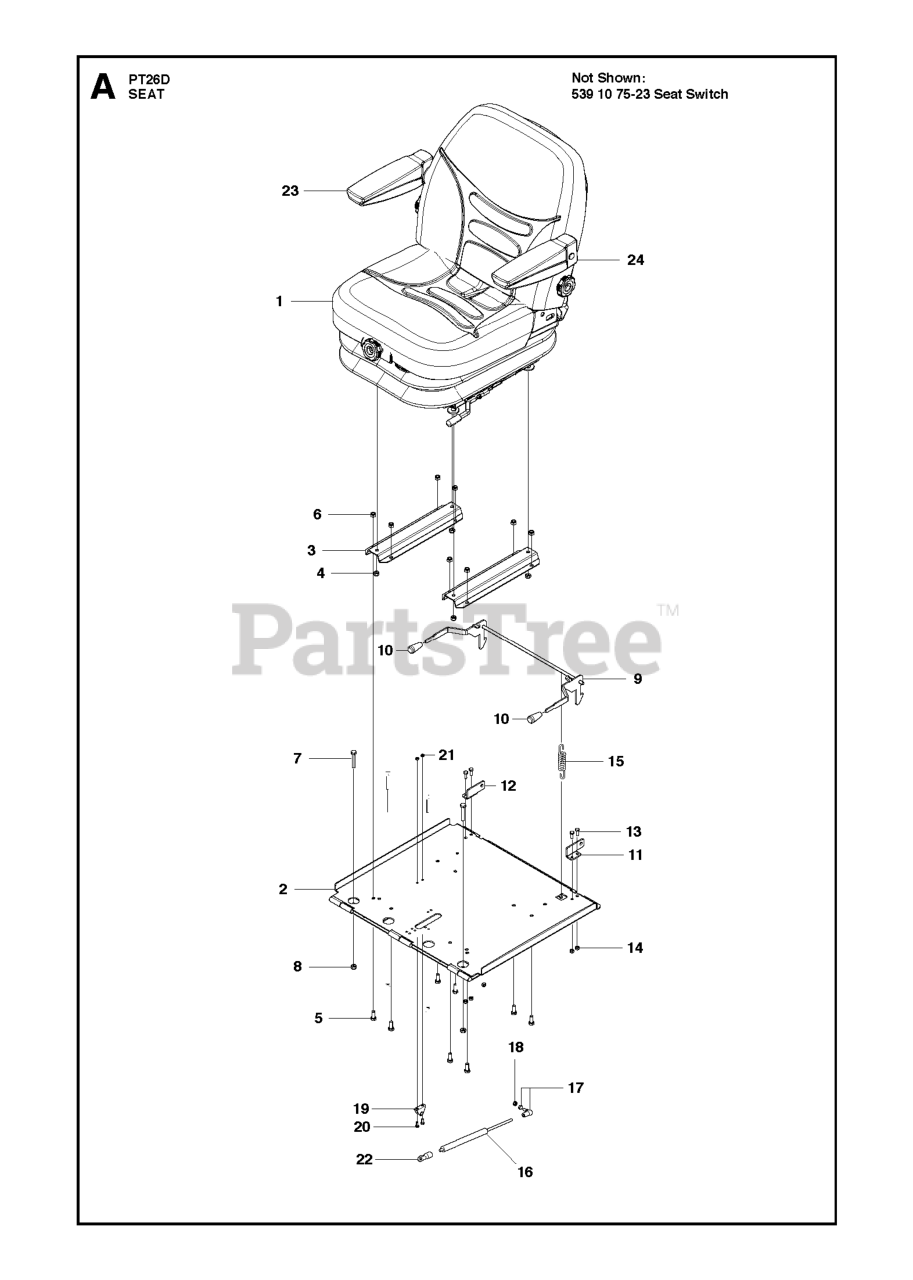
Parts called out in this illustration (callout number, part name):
4	LOCKNUT M8
5	SCREW 8X20
6	LOCKNUT M8
7	SCREW
8	LOCKNUT M8
13	Screw
14	LOCKNUT M6
15	DRAW SPRING L=50
18	LOCKNUT M6
20	SCREW
21	LOCKNUT M5
